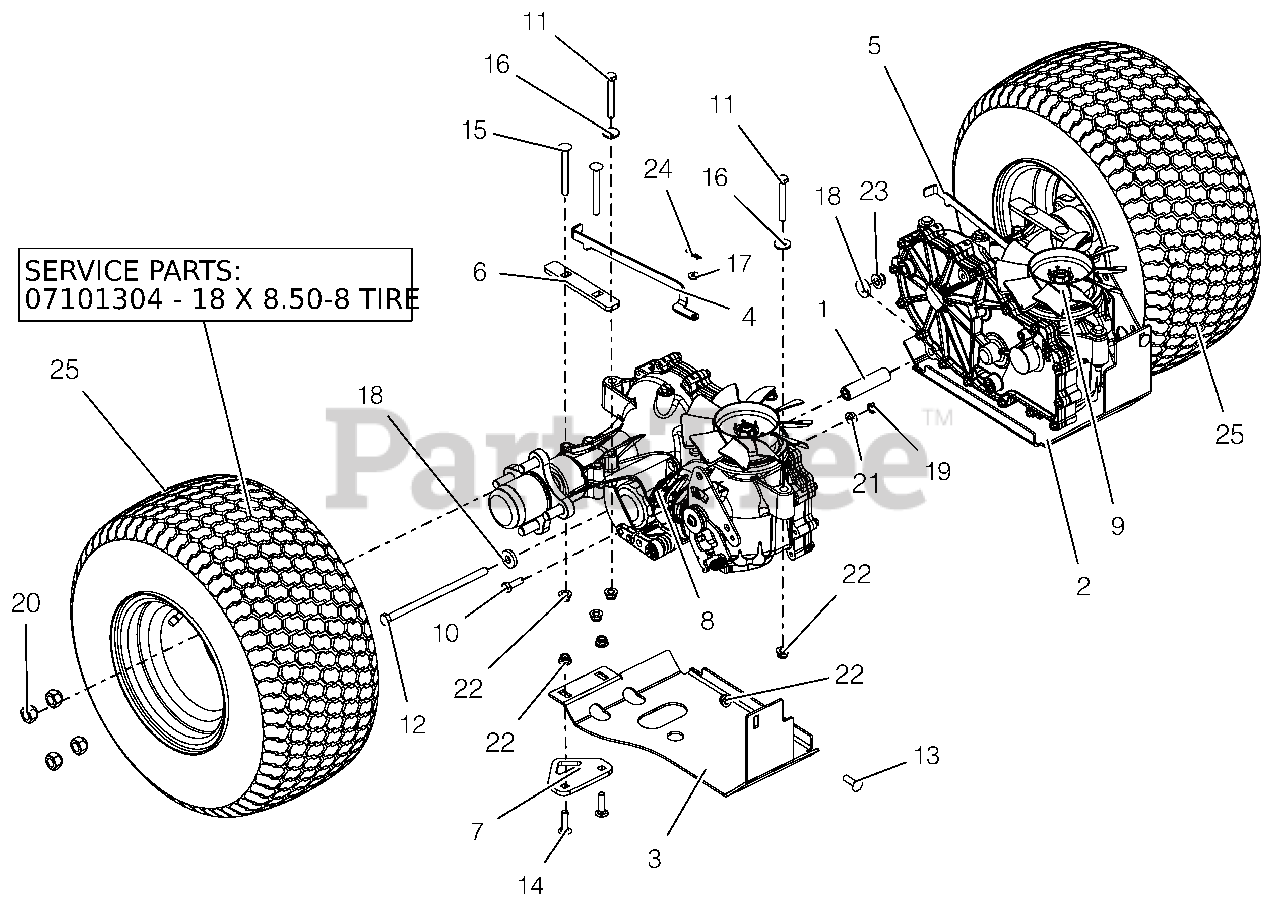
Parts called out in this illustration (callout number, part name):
1	SHAFT, CROSS BRACE
2	PLATE, TRANS SKID
3	PLATE, TRANS SKID
4	BRKT, LH DUMP VALVE
5	BRKT, RH DUMP VALVE
6	DOUBLER, TRANS MNT
7	BRKT, TIE DOWN LOOP
8	TRANSAXLE, RH - ZT31000
9	TRANSAXLE, LH - ZT3100
10	@BLT-HEX .31-18X1.00 GR5 YWZC
11	@BLT-HEX .31-18X2.50 GR5 YWZC
12	@BLT-HEX .38-16X7.00 GR5 YWZC
13	@BLT-RDHDSQNK .31-18X1.00 G5YZ
14	@BLT-RDHDSQNK .31-18X1.25 G5YZ
15	BLT-RDHDSQNK .31-18X3.00 G5YZ
16	@WSHR-FL-STL.38X.875X.083 YWZC
17	@WSHR-FL-STL.281X.62X.065 YWZC
18	WSHR-FL-STL .406X1.00X.188 YWZ
19	@NUT-LK-CTR-JAM .31-18 YWZC
20	WHEEL NUT .500-20 YZ
21	@NUT-SPNLK-FLG .312-18 YWZC
22	@NUT-LK-NYL-FLG .31-18 YWZC
23	@NUT-LK-NYL-FLG .38-16 YWZC
24	PIN-HAIR, ENDRIES #25 YWZC
25	ASM, WHL/TIRE 18X8.50-8
25	TIRE, 18 X 8.50-8
